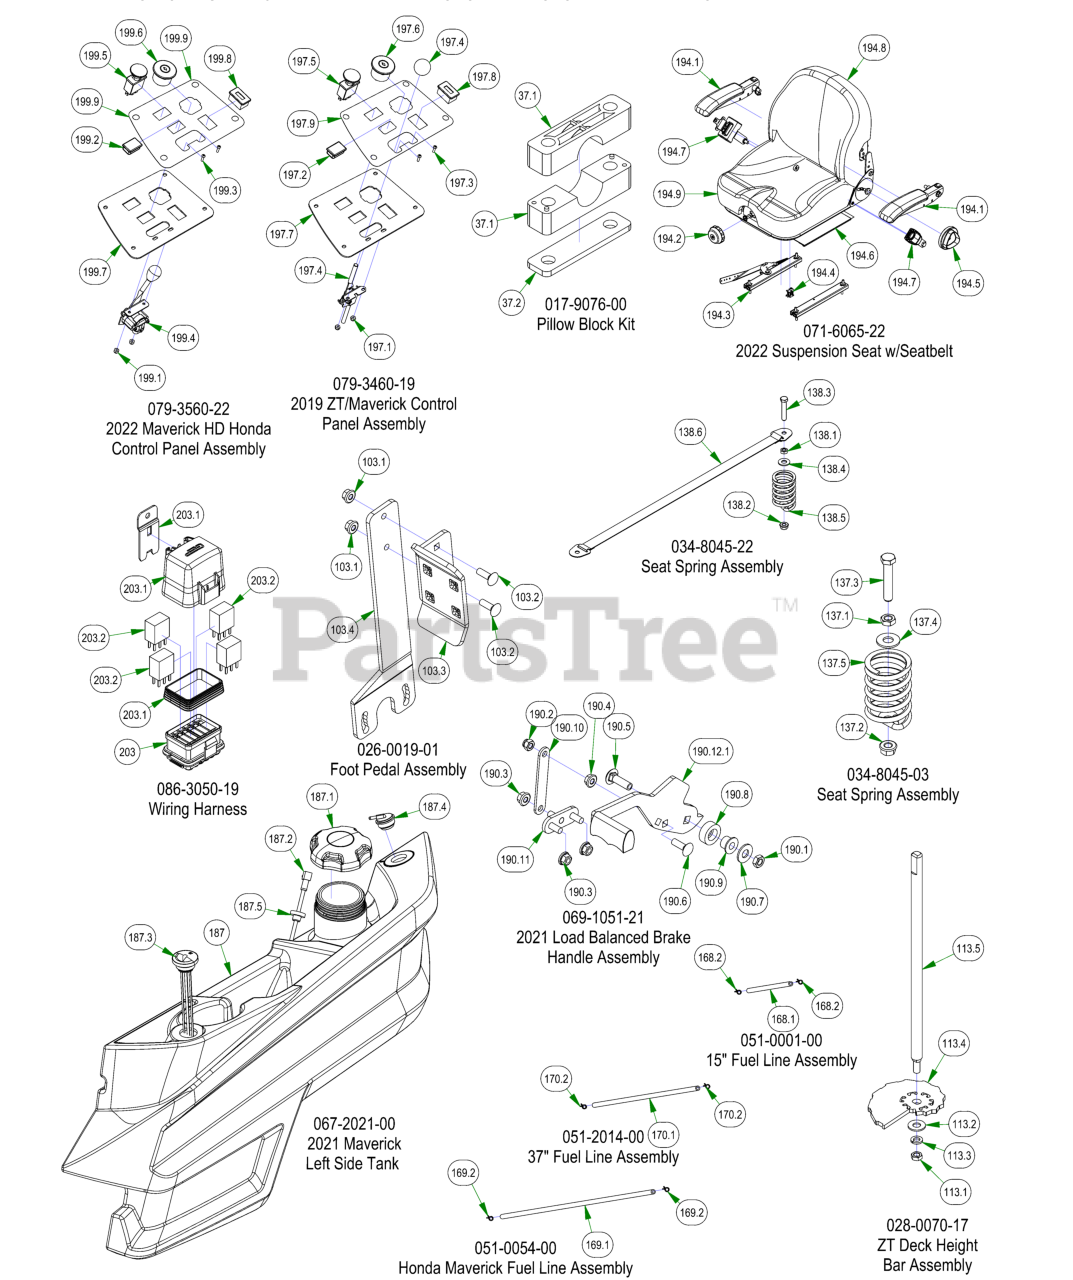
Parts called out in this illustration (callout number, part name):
37	Pillow Block Kit
37.1	Pillow Block MZ
37.2	Pillow Block Strap
103	Foot Pedal Assembly
103.1	5/16-18 NYLON INSERT FLANGE LOCKNUT ZINC
103.2	5/16-18 X 1 CARRIAGE BOLT (GR.8) ZINC
103.3	2017 MZ/ZT Shallow Foot Pedal
103.4	2017 MZ/ZT Deck Pedal Lever
113	ZT Deck Height Bar Assembly
113.1	3/8-24 HEX NUT ZINC YELLOW
113.2	3/8 FLAT WASHER USS (1" OD) ZINC
113.3	3/8 SPLIT LOCKWASHER ZINC
113.4	2017 MZ/ZT Cam Plate
113.5	2017 Deck Height Dial Rod ZT
137	Seat Spring Assembly
137.1	3/8-16 Half Jam Nut
137.2	3/8-16 HEX SERRATED FLANGE NUT HARD/ZINC
137.3	3/8-16 X 2 HEX CAP SCREW (GR.5) ZINC
137.4	3/8 FLAT WASHER USS (1" OD) ZINC
137.5	Seat Spring
138	Seat Spring Assembly
138.1	3/8-16 Half Jam Nut
138.2	3/8-16 HEX SERRATED FLANGE NUT HARD/ZINC
138.3	3/8-16 X 2 HEX CAP SCREW (GR.5) ZINC
138.4	3/8 FLAT WASHER USS (1" OD) ZINC
138.5	Seat Spring
138.6	Seat Strap with Buckles
168	15" Fuel Line Assembly
168.1	1/4 Fuel Line
168.2	1/4 Fuel Hose Clamp
169	Honda Maverick Fuel Line Assembly
169.1	1/4 Fuel Line, 54"
169.2	1/4 Fuel Hose Clamp
170	37" Fuel Line Assembly
170.1	37" 1/4 Fuel Line
170.2	1/4 Fuel Hose Clamp
187	2021 Maverick Left Side Tank
187.3	Fuel Gauge w/Grommet
187.4	Rollover Valve W/Grommet
187.5	Pick-Up Grommet
190	2021 Load Balanced Brake Handle Assembly
190.1	3/8-16 HEX JAM 2-WAY REVERSIBLE CENTER LOCKNUT ZINC
190.2	5/16-18 NYLON INSERT CAP LOCKNUT ZINC (BLK CAP)
190.3	5/16-18 NYLON INSERT FLANGE LOCKNUT ZINC
190.4	5/16-18 HEX SERRATED FLANGE NUT HARD/ZINC
190.5	3/8-16 X 1-1/4 CARRIAGE BOLT ZINC
190.6	5/16-18 X 1 CARRIAGE BOLT (GR.8) ZINC
190.7	3/8 FLAT WASHER USS (1" OD) ZINC
190.8	2015 Brake Lever Spacer
190.9	.377 ID X .625 OD X .500 HGT X .880 FLNG DIA X .060 FLNG THK
190.10	Brake Cable Extension Plate
190.11	Brake Load Balancer Lower Weldment
190.12	Load Balanced Brake Handle with Grip
190.12.1	Switch Relocation Brake Handle
190.12.2	Brake Handle Rubber
194	2022 Suspension Seat w/Seatbelt
194.1	Set of Armrests-SS Front Adj
194.2	Weight Adjust Indicator Knob Assy
194.3	4" Single Locking Track Kit
194.4	Delta Plunger Switch - N.O.
194.5	Recliner Adjustment Knob-New
194.6	Bellows w/Hardware
194.7	2" Retractable Belt Kit w/Spacers
194.8	Back Cover for I3M - Recl - Logos
194.9	Cushion Cover Kit for I3M-Logo
197	2019 ZT/Maverick Control Panel Assembly
197.1	10-24 Nylon Insert Locknut Zinc Orange Nylon
197.2	Light Plug
197.3	10-24 X 5/8 BS Button Head Bolt
197.4	Throttle Lever Assembly
197.5	PTO Engager
197.6	Ignition Switch
197.7	2014 ZT Control Panel
197.8	Tachometer
197.9	Rambler Instrument Panel Decal
199	2022 Maverick HD Honda Control Panel Assembly
199.1	10-24 Nylon Insert Locknut Zinc Orange Nylon
199.2	Light Plug
199.3	10-24 X 5/8 BS Button Head Bolt
199.4	Honda Drive By Wire
199.5	PTO Engager
199.6	Ignition Switch
199.7	2022 Maverick HD control panel
199.8	Tachometer
199.9	2023 MZ/Magnum/ZT/Maverick Control Panel Decal
203	Wiring Harness
203.1	Relay Block Cover Replacement Kit
